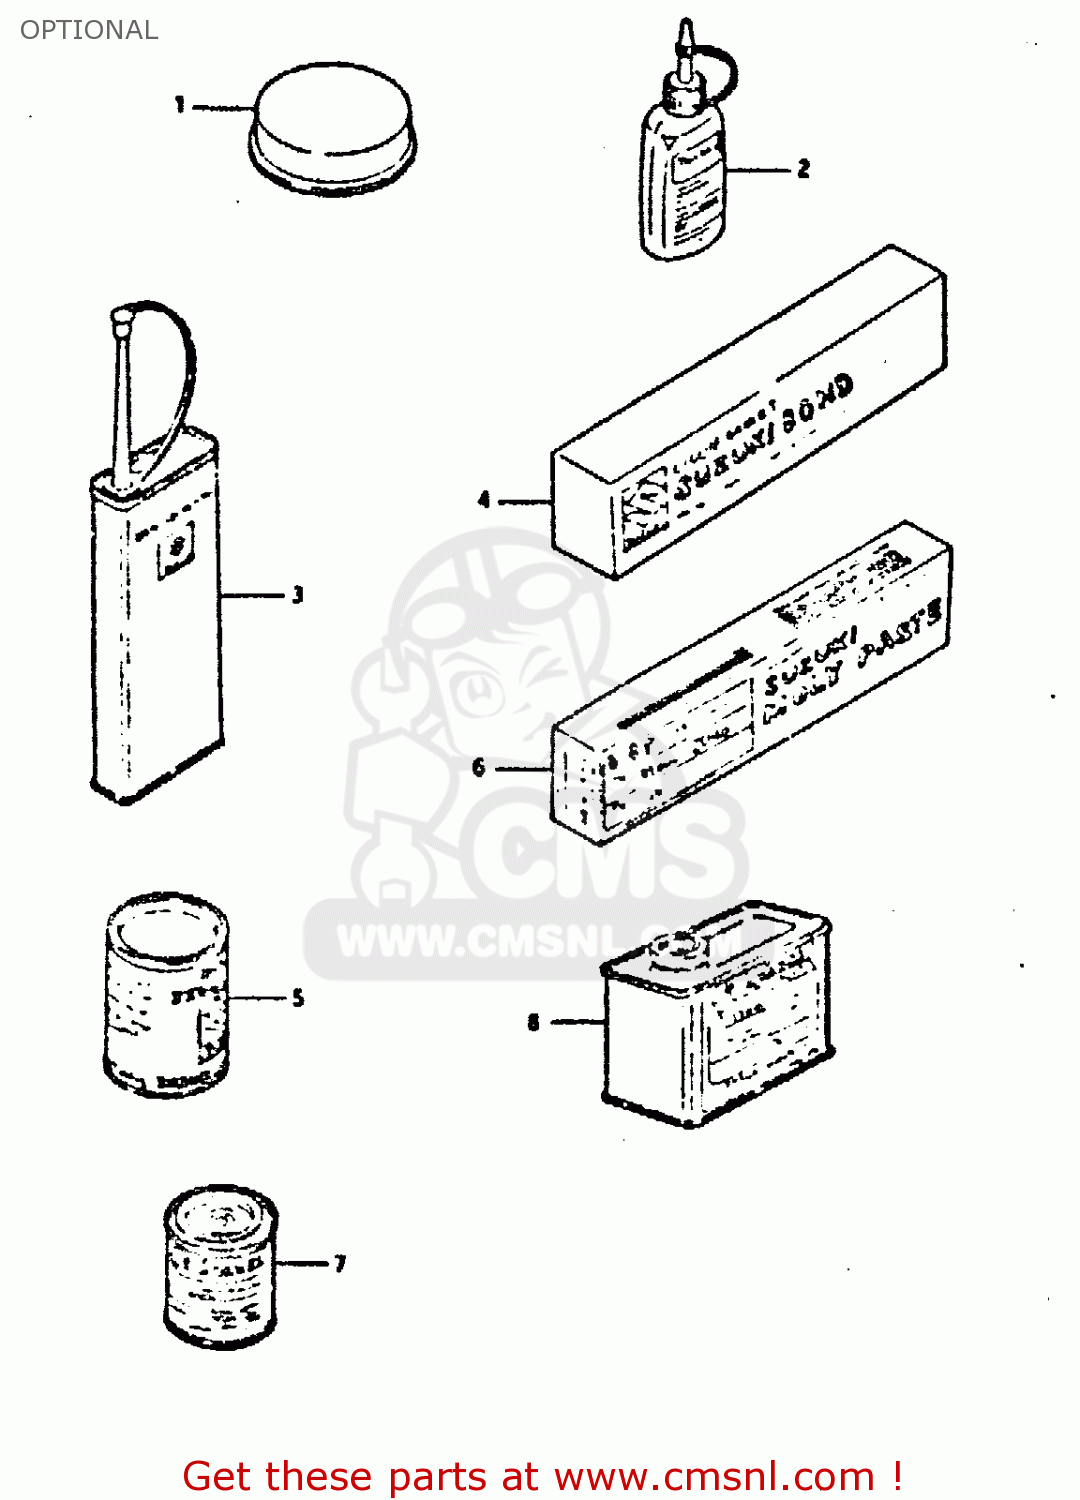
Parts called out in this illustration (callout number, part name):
1	GREASE,PBC FOR BRK PAD 20G
2	THREAD LOCK NO.1305 GREEN 50G
3	THREAD LOCK NO.1401 CLEAR 200G
4	LIQUID GSKT NO.1215 250G
5	GREASE(C)EP2 LITHIUM 150G
6	SUZUKI MOLY PASTE
7	PAINT,BLACK
8	PAINT (BLACK)
